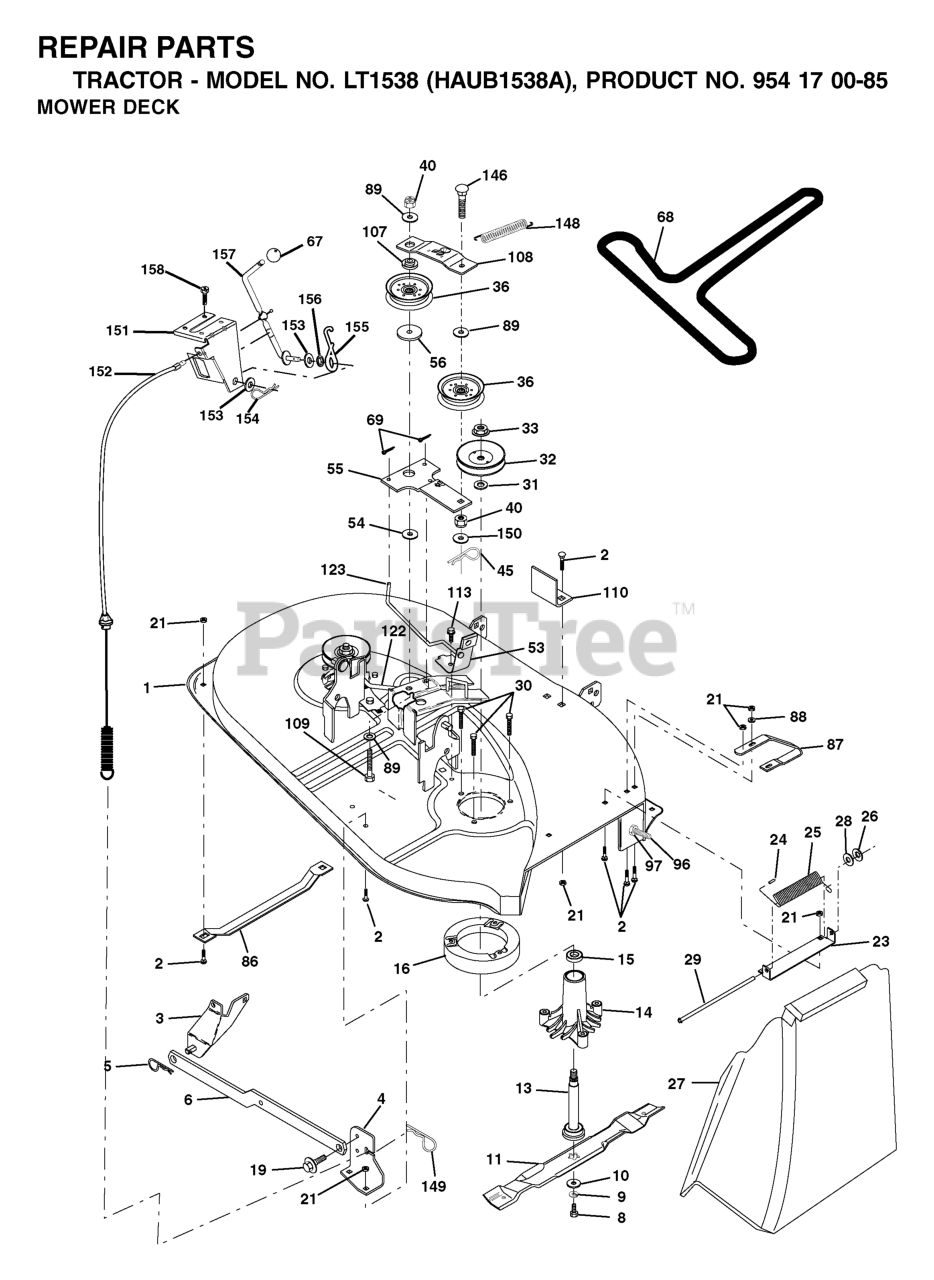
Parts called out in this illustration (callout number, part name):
1	MOWER HOUSING ASM
2	RP BOLT 5/16-18 X3/4 ZN/YEL GR
3	BRKT ASM SWAY BAR
4	BRACKET DECK SWAY BAR 38/42"
5	RETAINER-SPRNG RB
6	BAR SWAY DECK
8	BLADE BOLT
9	LOCKWASHER
10	WASHER.BLADE
11	BLADE.HI.LIFT.38"
13	SHAFT ASM VENT
14	HOUSING.MANDREL.VENTED (MACHD)
16	STRIPPER.MANDREL.ROUND.BLACK
19	BOLT SHD 5/16-18
21	LOCKNUT
23	BRACKET, DEFLECTOR
24	CAP-SLEEVE LT
25	SPRING TORSION
26	NUT PUSH M
27	SHIELD, DEFLECTOR
28	Washer 11/32 x 5/8 x 16 Ga SD
29	ROD-HINGE T
30	SCREW, WASHER HEAD
31	WASHER
32	PULLEY MANDREL
33	NUT, FLG TOPLOCK 9/16"
36	FLAT IDLER PULLEY
45	RETAINER M
53	BRAKE ASSEMBLY
54	HARDENED WASHER
55	IDLER ARM
56	SPACER.RETAINER.MOWER
67	KNOB T (3/8 HOLE)
68	V-BELT TRIPATH
69	COTTER PIN
86	RUNNER-LH M
87	RUNNER.RH.38
88	WASHER M
89	WASHER GT
107	SPACER.IDLER.ARM
108	STIFFENER.IDLER.ARM
109	Bolt Hex Fin 3/8-16 UNC x 2-1/2
110	UPSTOP DECK FRONT 38"
113	SCREW 5/16"
122	BRAKE ROD LH
123	ROD.BRAKE.MANDREL.RH
146	BOLT, CARRIAGE IDLER
148	IDLER RETURN SPRING
149	SPRING.RETAINER.YELLOW.ZINC
150	WASHER PM
151	BRACKET.CLUTCH.CABLE
152	CLUTCH CABLE 38"/46"
153	WASHER FLAT 3/8"
154	SPRING RETAINER
155	SPRING RETENTION LEVER
156	SPACER.CLUTCH.CABLE
157	ROD CLUTCH CABLE 3/8"
158	SCREW
